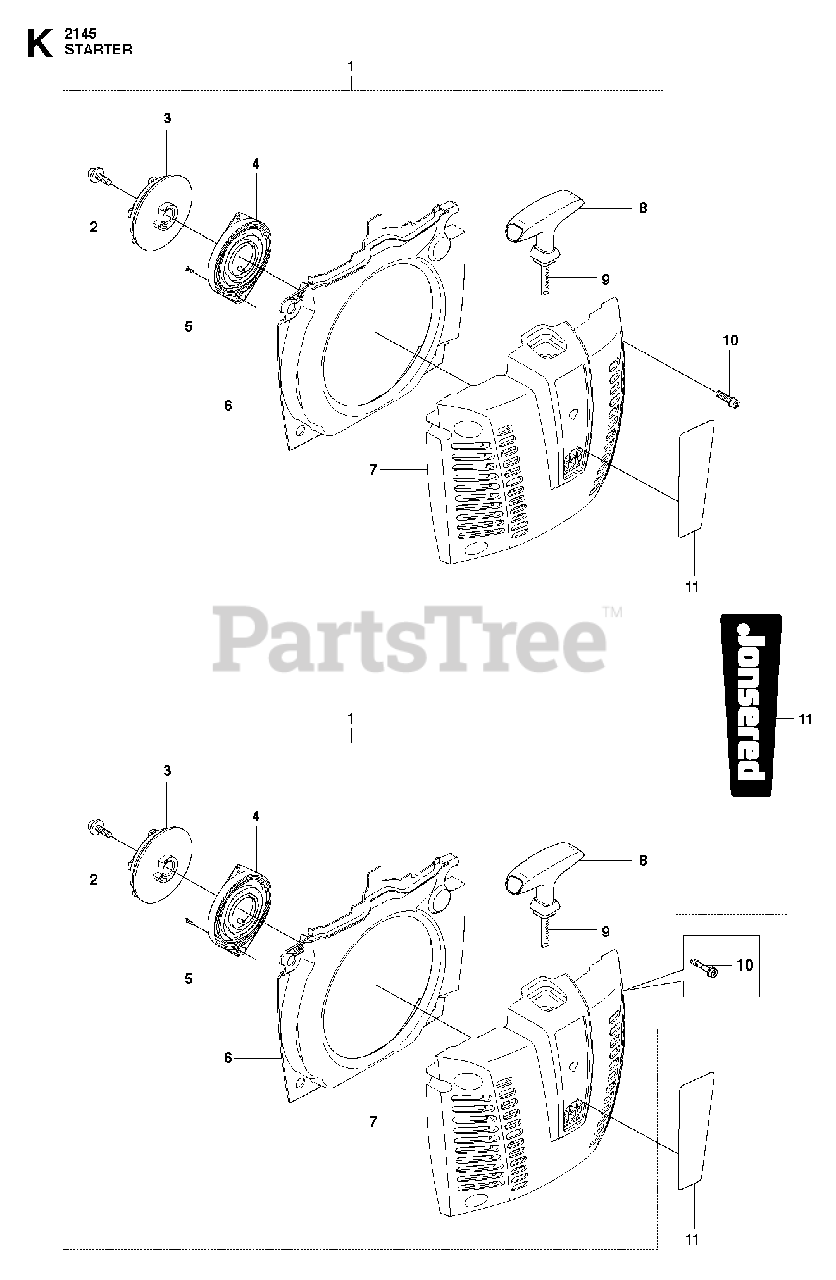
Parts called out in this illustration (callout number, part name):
2	SCREW
3	STARTER PULLEY
4	RECOIL SPRING
5	SCREW
6	AIR CONDUCTOR
7	STARTER HOUSING
8	STARTER HANDLE
9	STARTER ROPE
10	SCREW IHSCFM
10	SCREW IHSCFMO
11	STARTER HOUSING DECAL
